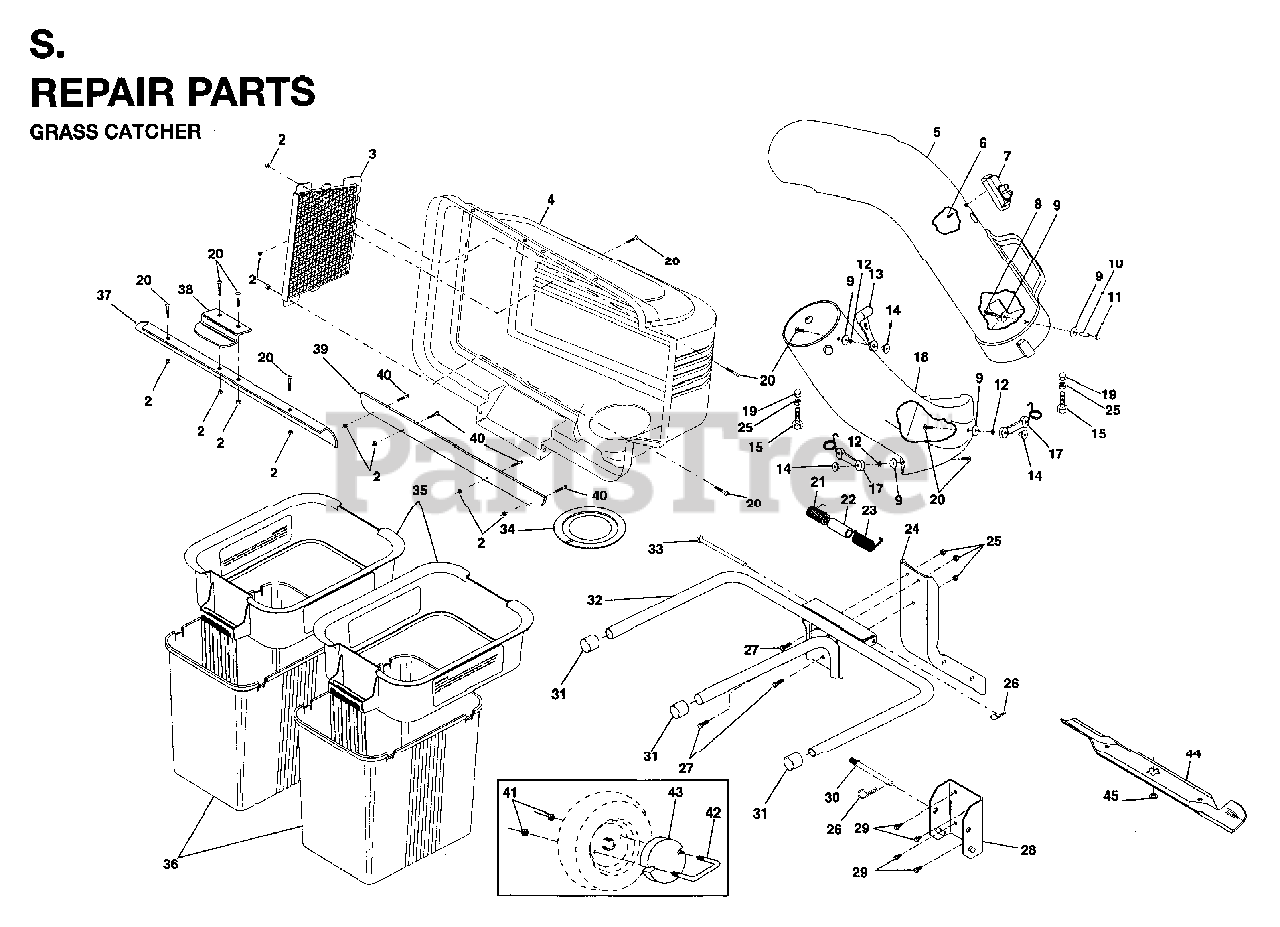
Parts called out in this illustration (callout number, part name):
3	COVER SCREEN
4	COVER BAGGER TOP
5	UPPER CHUTE
7	INDICATOR DUMP BAG
8	RP SCREW
10	SPACER LT
11	NUT
12	LOCKWASHER
13	HOOD LATCH T
14	NUT.WELD.#10-24
17	LATCH ASSEMBLY
18	CHUTE LOWER 36"
19	ACORN NUT
20	SCREW.10-24X5/8
21	SPRING COVER LH
22	SPACER.COVER.BAGGER
23	SPRING COVER RH
24	SUPPORT POST
25	LOCKNUT
26	RETAINER SPRING
27	BOLT
28	MTG BRACKET
30	SUPPORT POST PIN
31	TUBING PLUG
32	BAGGER FRAME
33	HINGE PIN
34	GASKET COVER
35	CONTAINER TOP
36	CONTAINER BOTTOM
37	SEAL, COVER
38	LATCH CER38
39	SEAL STRIP
41	LOCKNUT
43	WEIGHT, FRT WHEEL
44	BLADE, HI-LIFT 36" PREMIUM
